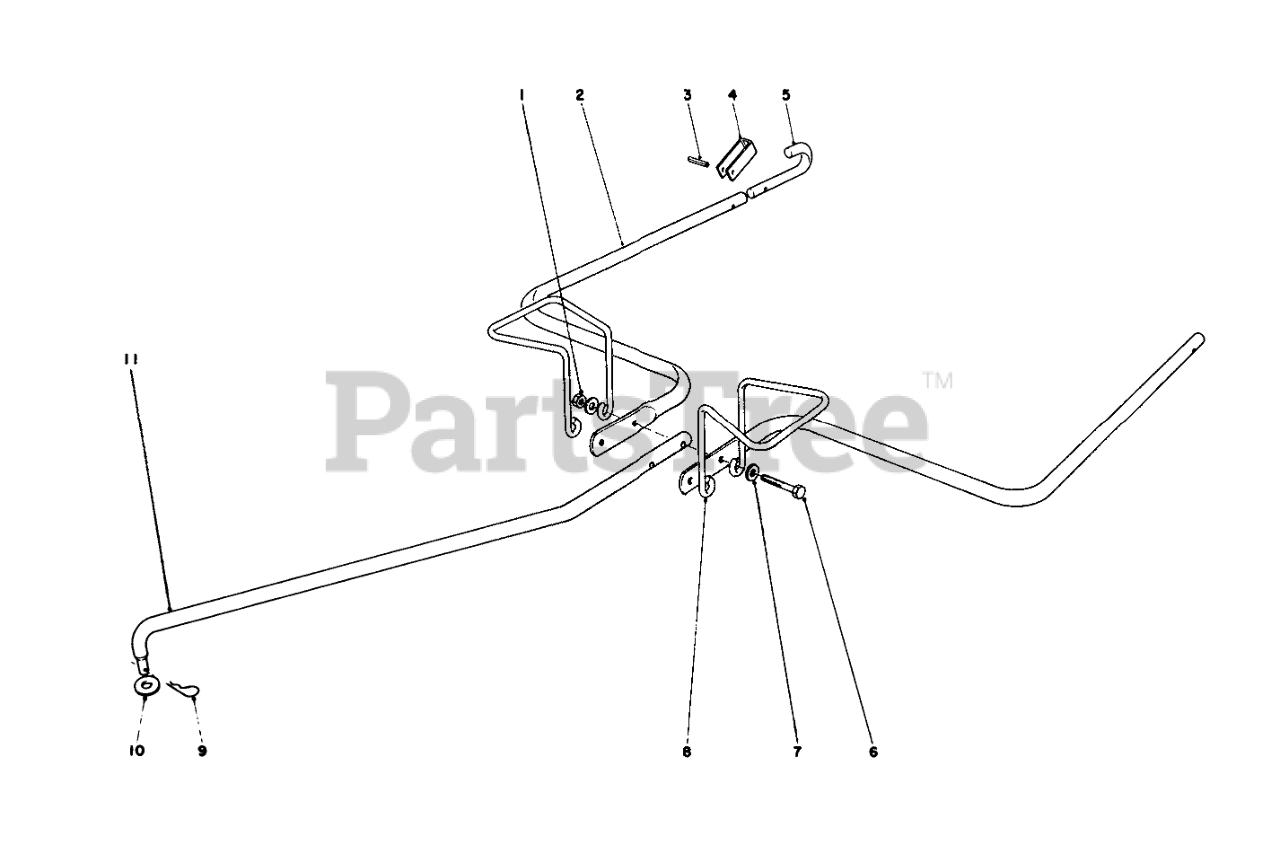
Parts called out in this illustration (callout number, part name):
1	NUT-LOCK, CONE
2	HITCH ARM
3	PIN-ROLL, SLOT
4	HITCH LOCK
5	HOOK HITCH ARM
6	SCREW-HH
7	WASHER-FLAT
8	Support Bag
9	PIN-COTTER
10	PUSH NUT
11	POLE HITCH
